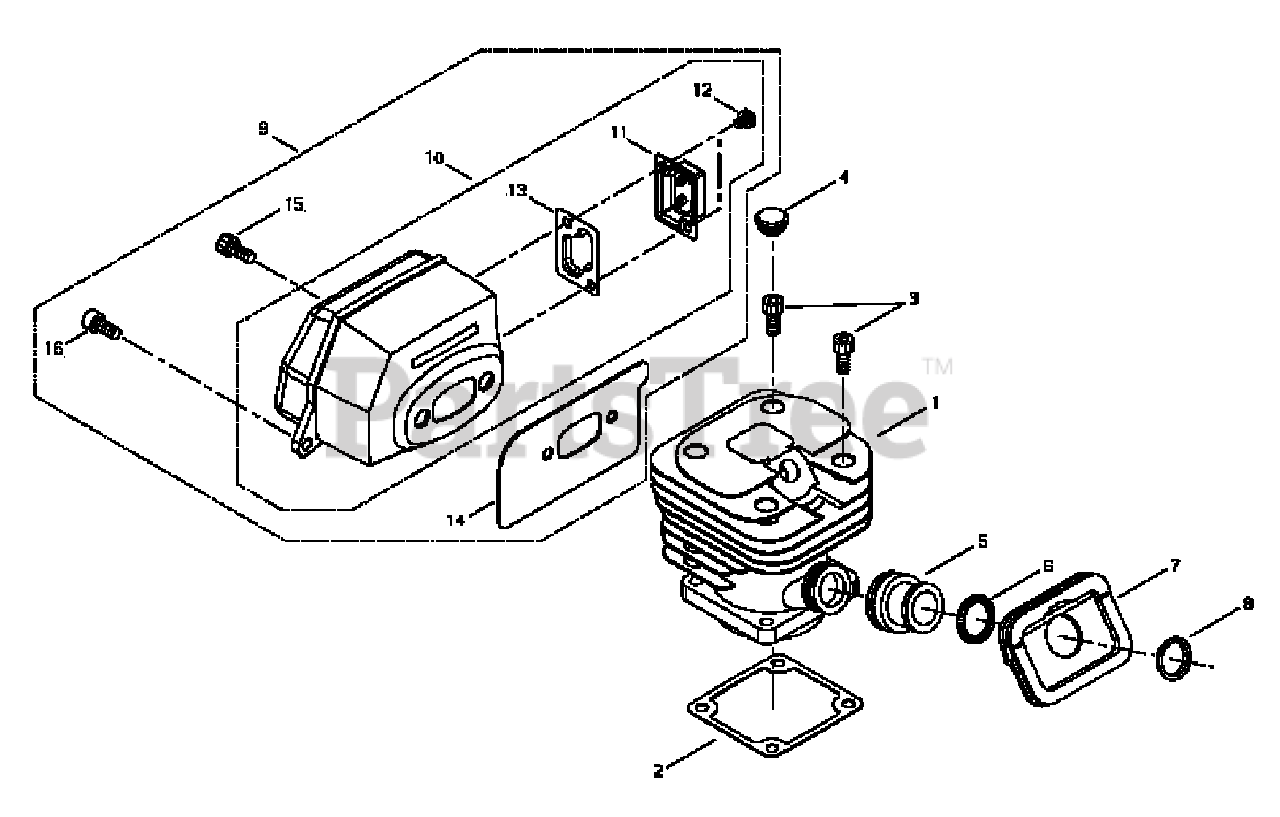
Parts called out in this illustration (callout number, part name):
1	CYLINDER
2	GASKET, CYLINDER
3	BOLT M5×18
4	PLUG
5	BOOT
6	SPRING
7	SEAL
8	SLEEVE
9	MUFFLER ASSY
10	MUFFLER ASSY
11	COVER, SPARK ARRESTER
12	SCREW M4×6
13	SCREEN, SPARK ARRESTER
14	GASKET
15	BOLT M5×18
16	BOLT
